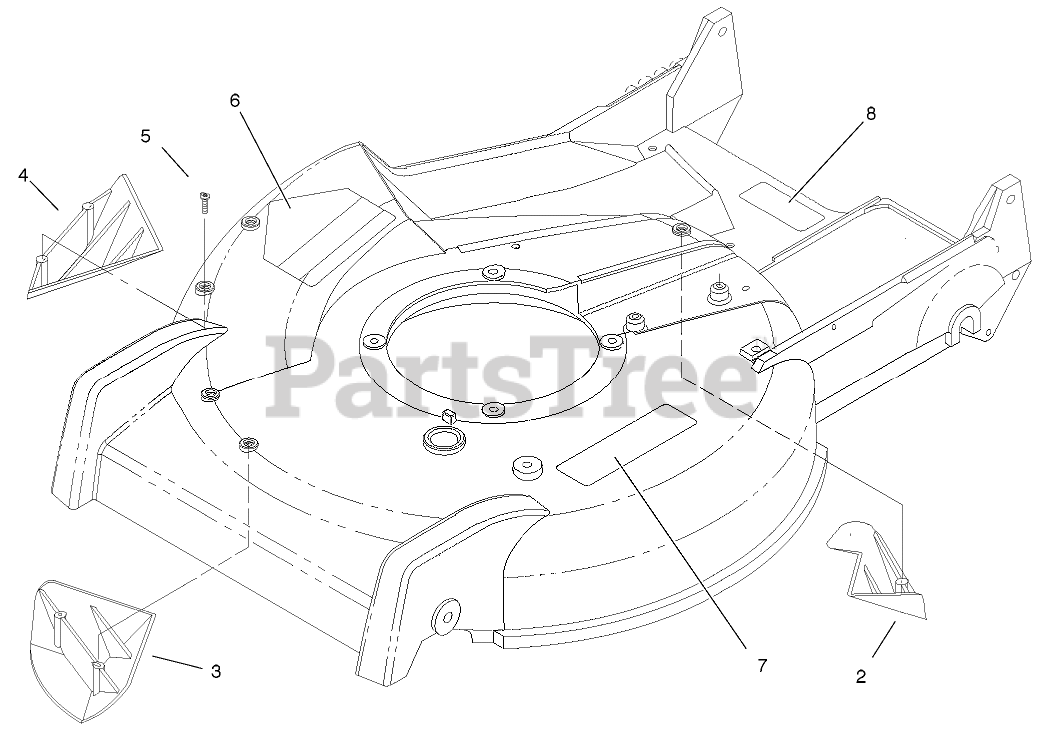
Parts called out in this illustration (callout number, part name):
2	KICKER-REAR
3	KICKER-FRONT
4	KICKER-RH
5	SCREW-PPH
6	DECAL-DANGER
7	DECAL-WARNING
8	DECAL-WARNING
